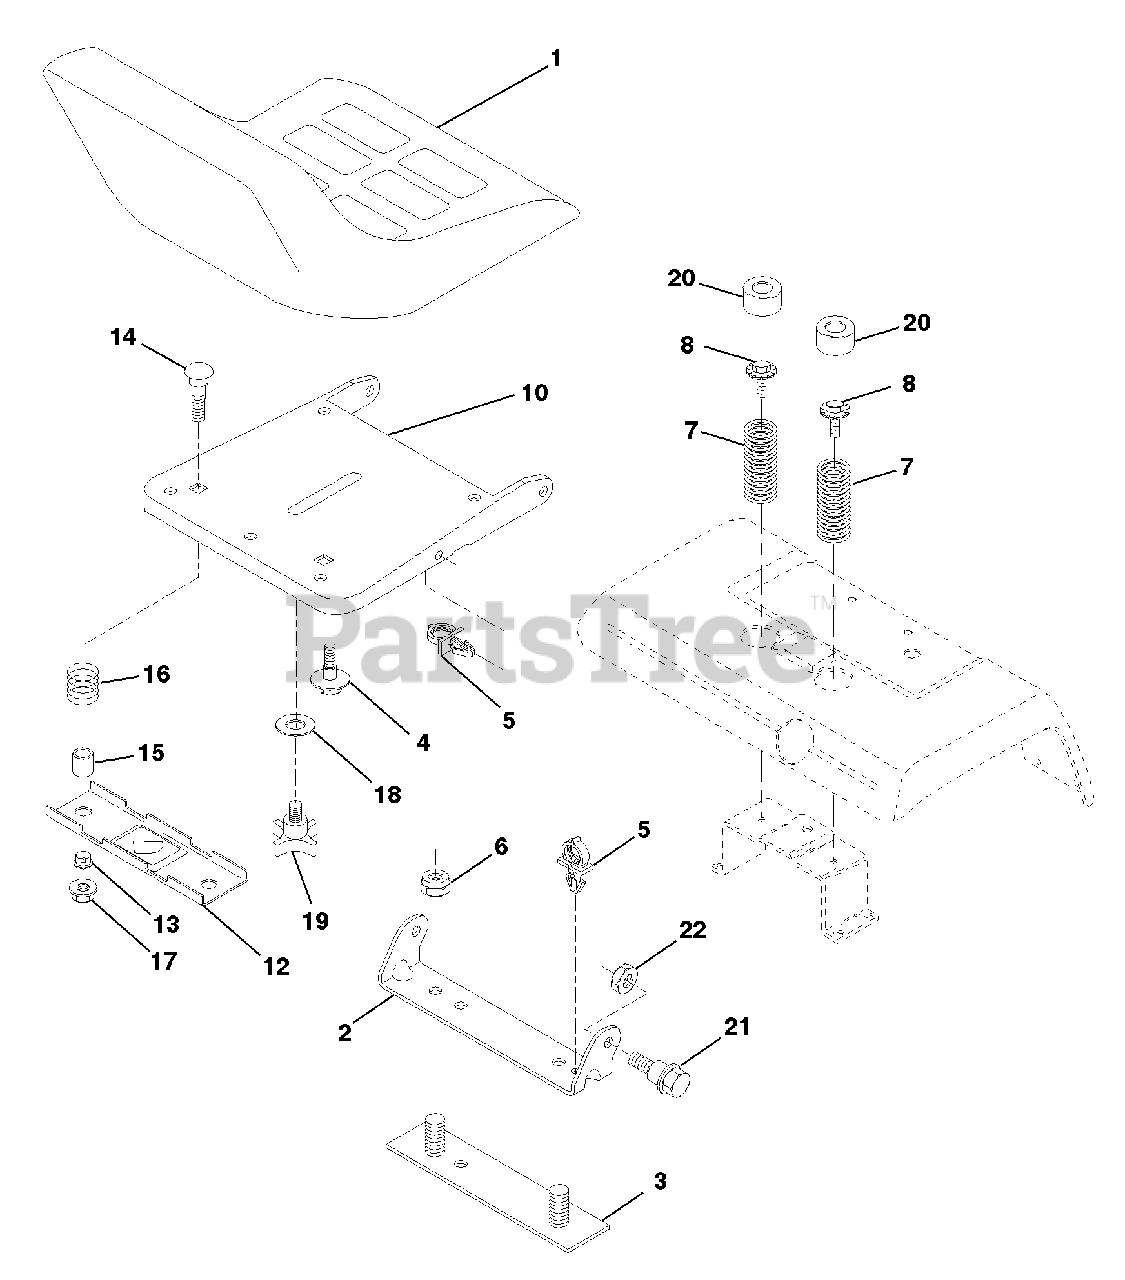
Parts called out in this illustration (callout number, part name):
1	Seat
2	Bracket, Pivot Seat
3	Strap, Fender
4	Bolt, Shoulder 5/16-18 X .62
5	Clip, Push In Hinged
6	Nut, Lock Hex W/Ins. 3/8-16 Unc
7	Spring, Seat Cprsn
8	Bolt 5/16-18unc x 3/4 W/Sems
10	Pan, Seat
12	Bracket, Mounting Switch
13	Bushing, Snap
14	Bolt, Carriage 1/4-20 X 1-1/2
15	Spacer, Split
16	Spring, Cprsn
17	Nut, Lock 1/4 Lge Flg Gr. 5
18	Washer 17/32 X 1-3/16 X 12 Ga.
19	Knob, Seat 1/2-13 Unc
20	Cap, Spring Seat
21	Bolt, Shoulder 5/16-18 Unc-2A
22	Nut, Crownlock 5/16-18 Unc
